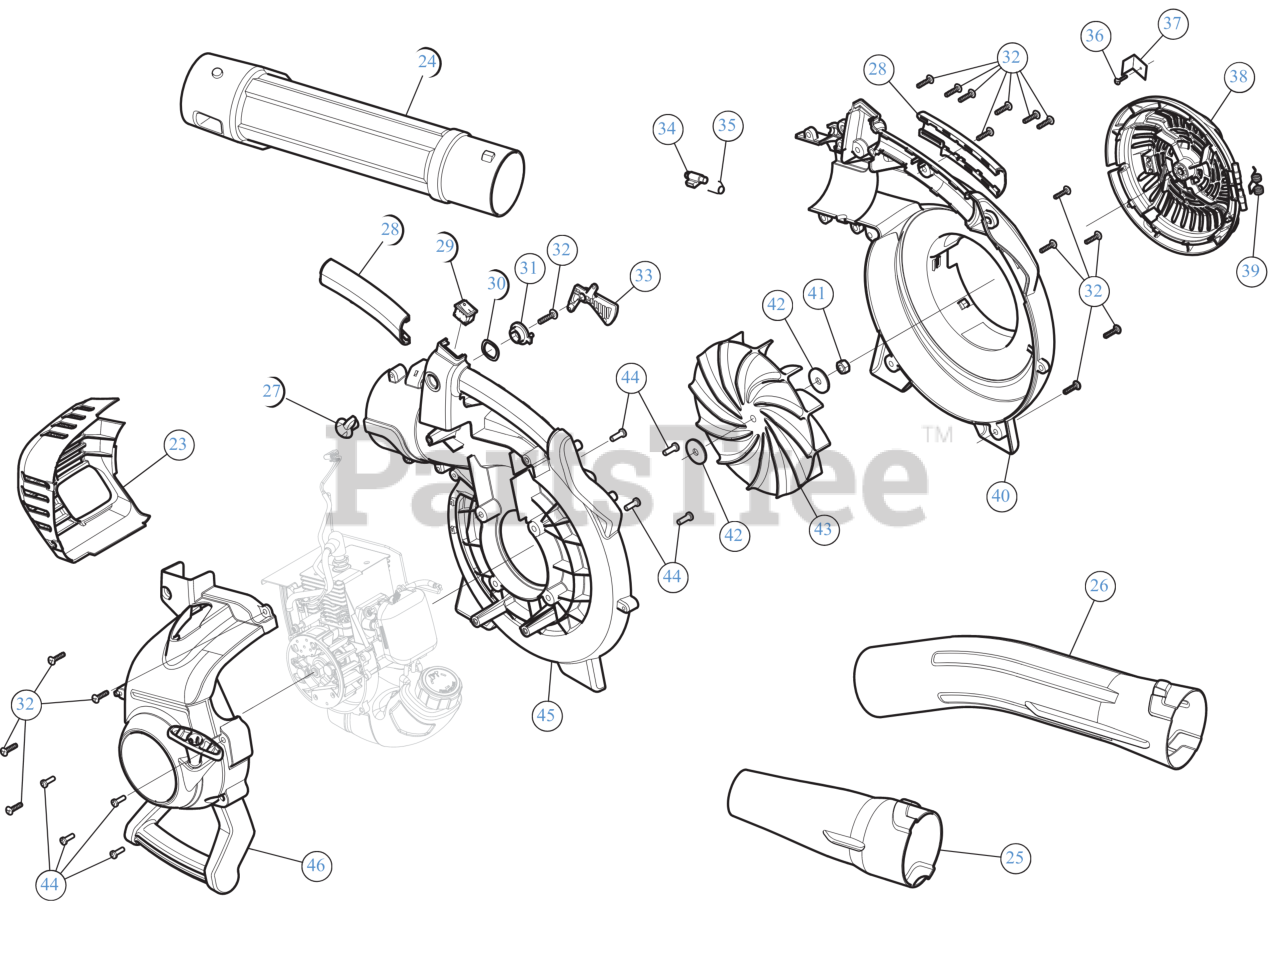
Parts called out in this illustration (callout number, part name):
23	MUFFLER COVER
24	UPPER TUBE
25	NOZZLE BKPK CUB
26	CURVED LOWER TUBE
27	TRIGGER LOCK OTR
28	ANDLE GRIP ASSEMBLY
29	SW, MOMENTARY ON/O
30	WAVE WASHER
31	TRIGGER LOCK INR
32	SCREW 8-16 x 3/4
33	THROTTLE TRIGGER
34	LATCH TUBE
35	SPRING LATCH
36	SCREW-10-9 x .50
37	DOOR LOCK SC
38	INTAKE COVER
39	SPRING
40	IMPELLER HOUSING OTR
41	HEX NUT
42	WASHER FLAT
43	IMPELLER
44	SCREW:10-32X.562:#8P
45	IMPELLER HOUSING INR
46	STARTER HOUSING ASSEMBLY
